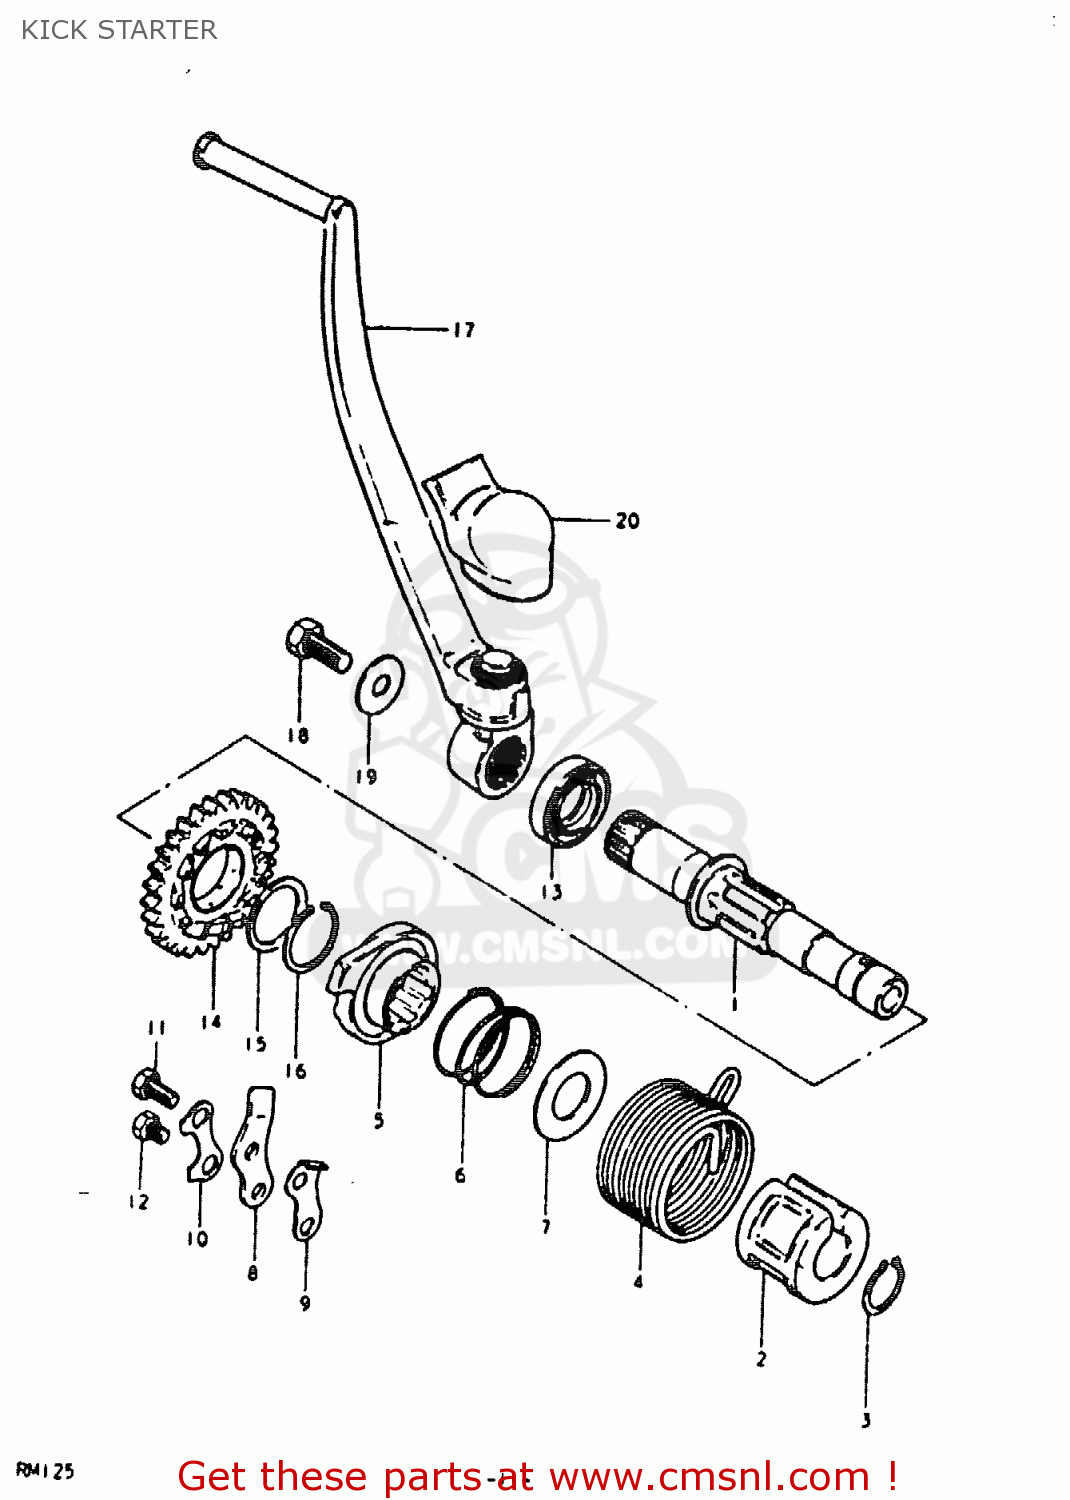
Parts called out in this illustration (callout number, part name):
1	SHAFT,KICK STARTER
2	GUIDE,KICK STARTER SFT SPRING
3	CIRCLIP
4	SPRING
5	STARTER,KICK
6	SPRING
7	WASHER
8	GUIDE,KICK STARTER
9	STOPPER,KICK STARTER
10	WASHER
11	BOLT, UPPER
12	BOLT
13	SEAL,OIL(20X27X5)
14	GEAR,KICK STARTER DRIVE
15	SHIM
16	CIRCLIP
17	LEVER ASSEMBLY,KICK STARTER
18	BOLT
19	WASHER(8.2X23X3.2)
20	COVER,KICK LEVER JOINT
